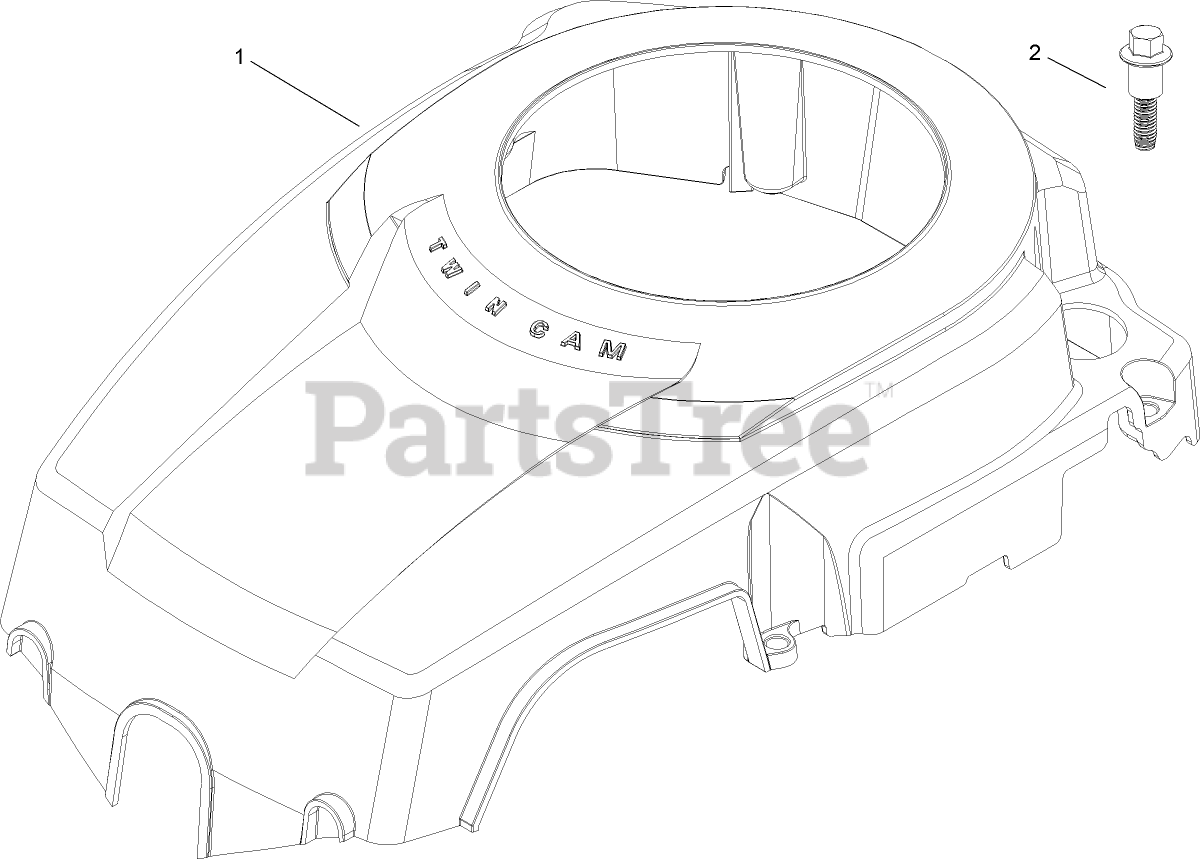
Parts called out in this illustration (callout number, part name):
1	Housing-Blower
2	Bolt-Shoulder (M6x1x26)
3	Decal-Wing
4	Decal
5	DECAL-LAMINATE, CLEAR
